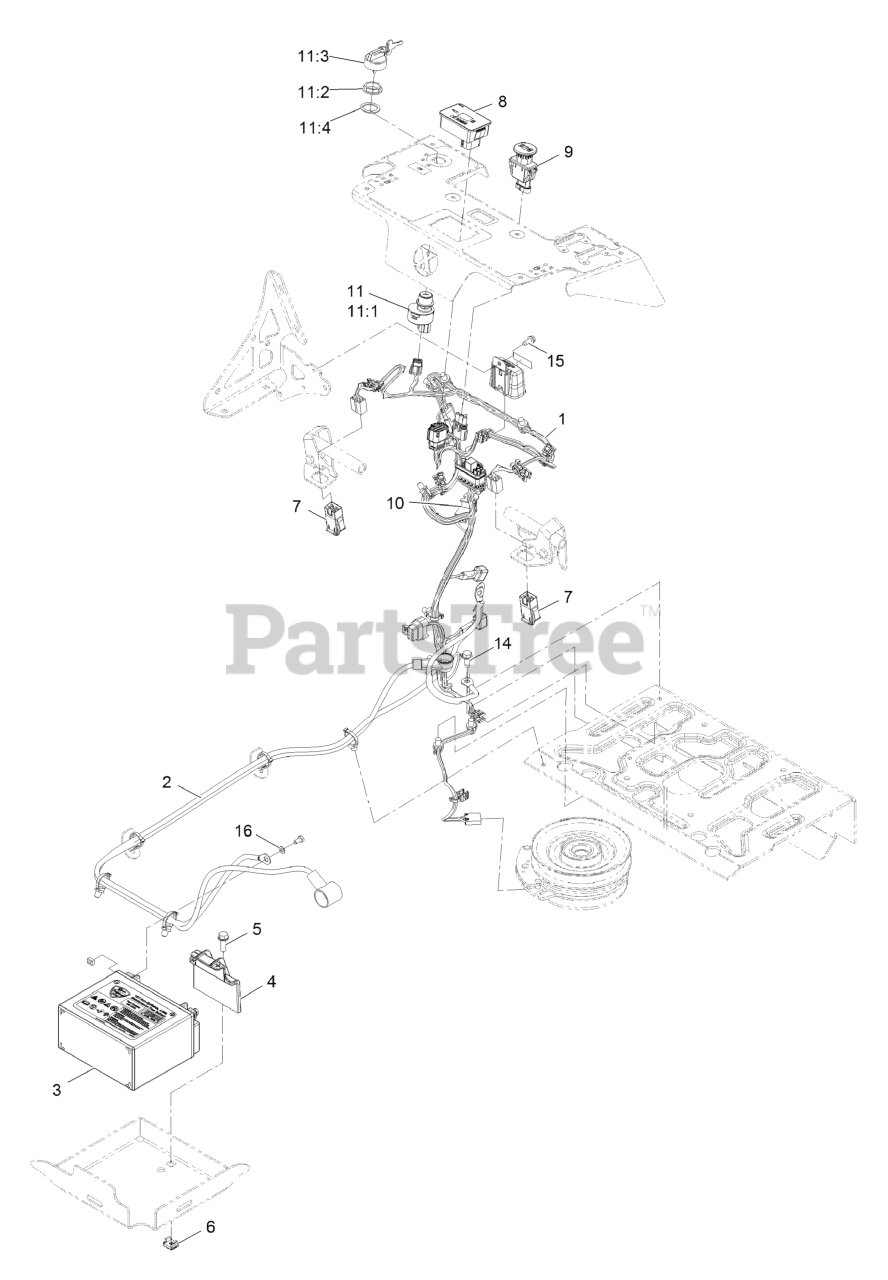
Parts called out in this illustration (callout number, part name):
1	HARNESS-WIRING
2	HARNESS-BATTERY
3	BATTERY, AGM, NON-SPILLABLE
4	HOLD DOWN, BATTERY
5	SCREW-HHF
6	NUT, SNAP
7	SWITCH-DELTA
8	Module-Hour Meter
9	SWITCH-PTO, SEALED
10	SWITCH-BAIL
11	IGNITION SWITCH ASM
11:1	Switch-Ignition
11:2	NUT-MOUNTING
11:3	IGNITION KEY SET
11:4	WASHER-BACKUP
14	SCREW-THD ROLL, HWH
15	SCREW-HWH
16	WASHER-SPRING
